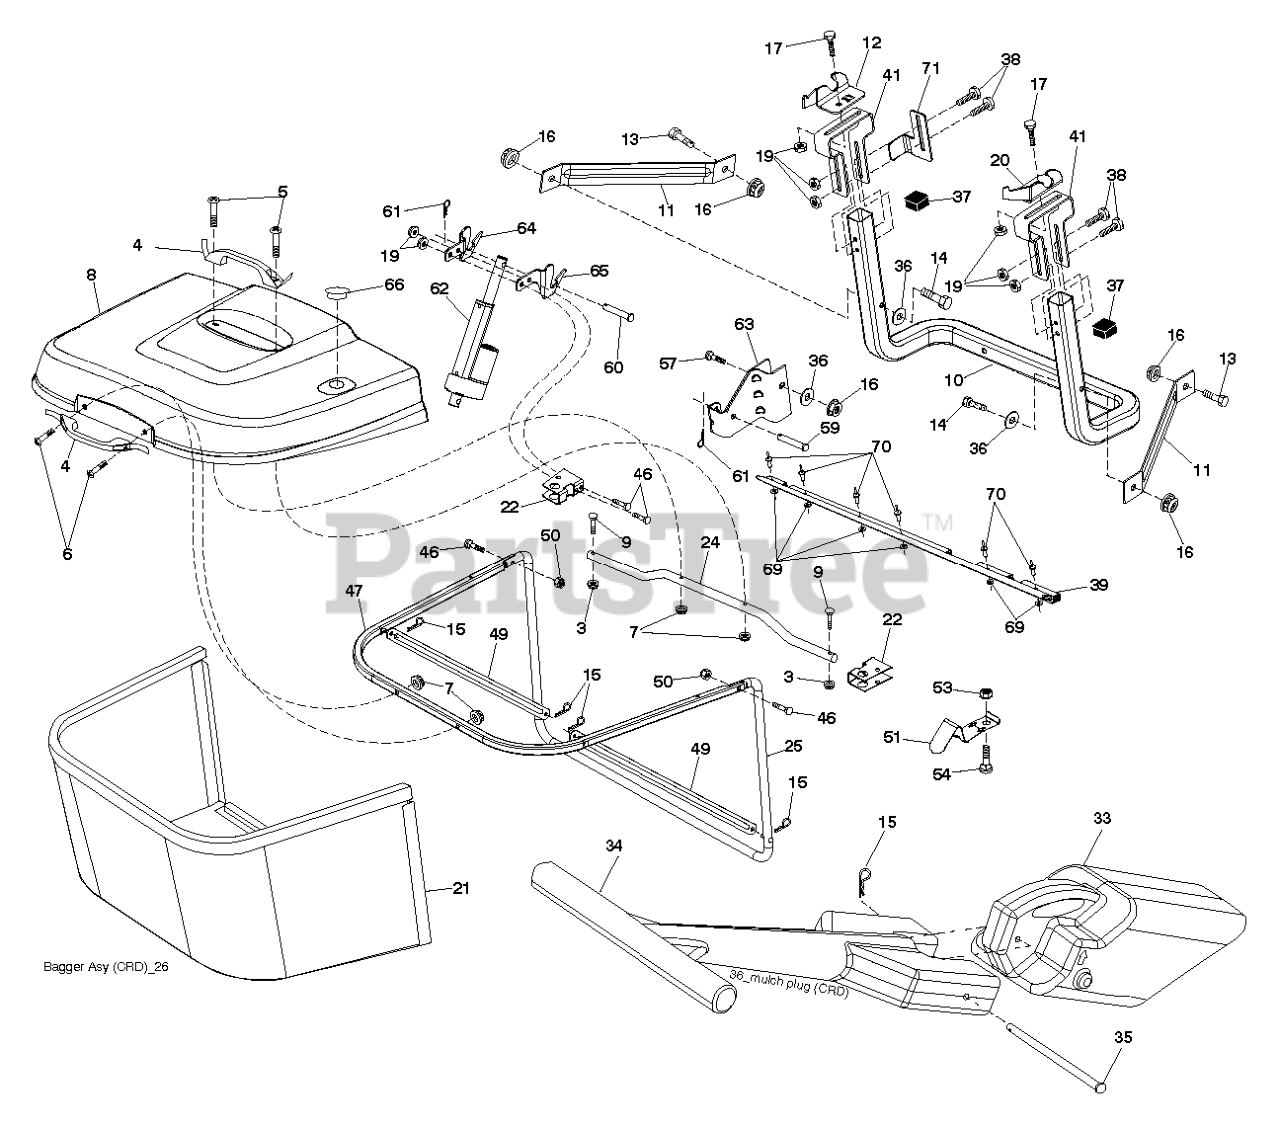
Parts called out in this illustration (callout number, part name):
3	NUT T
4	HANDLE.BAGGER.W/LVRS.BLK.CRD
5	SCREW.PAN.HEAD
6	REPL BY 532 75 00-29
8	BAGGER.COVER.SEAL.ASM.CRD.668
9	Bolt Carriage 1/4-20 x 2.25d x Gr.5
10	TUBE
11	BRACKET.SUPPORT.UPPER.BAG.CRD
12	BRKT PIVOT
14	BOLT-HEX EAK
15	RETAINER-SPRNG RB
16	NUT LOCK FLG 3/8-16 UNC
17	RP BOLT 5/16-18 X3/4 ZN/YEL GR
19	NUT LOCK HEX FLANGE 5/16-18
20	BRKT.PIVOT.RH.CRD
21	BAGGER.ASM.CRD.2007
22	BRACKET.BAGGER.SD.ELECTRIC.CRD
24	TUBE.PIVOT.BAG.CRD.BLACK
25	PIPE
33	MULCHING.PLUG.107.CRD.(2 2)
34	HANDLE.MULCHER.92.CRD (2 2)
36	WASHER
37	Plug Support Bagger CRD
38	BOLT.5/16-18X2.5
39	SEAL.BAGGER.CRD
41	BRACKET.BAGGER.SD.ELECTRIC.CRD
46	BOLT.CARRIAGE.5/16-18
47	PIPE
49	ROD
50	NUT.71038.31-18.HEX.NYLOCK
51	LATCH
53	NUT
54	BOLT
57	BOLT
61	RETAINER M
69	WASHER
70	RIVET RIVET POP
